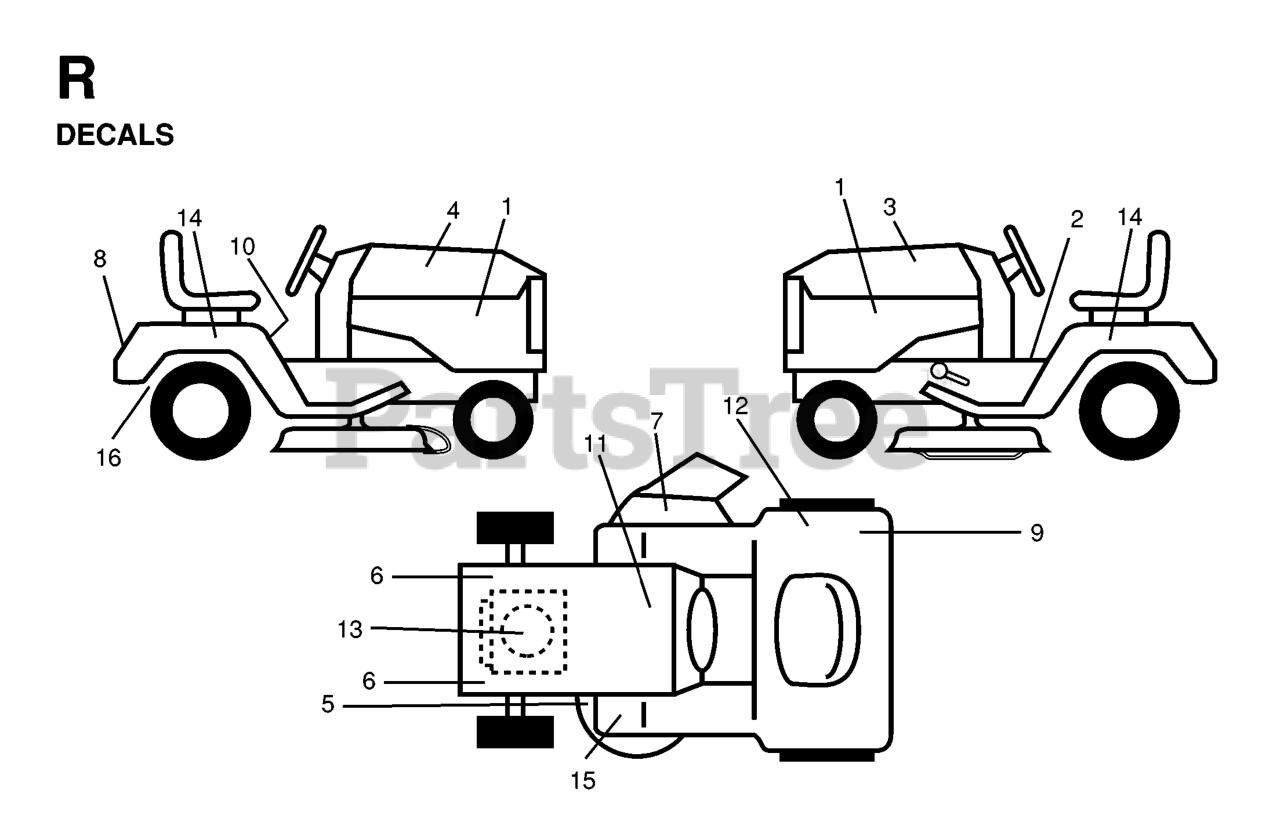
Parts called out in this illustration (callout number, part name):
1	DECAL PNL SIDE
2	DECAL PARK BRAKE
3	HOOD DECAL LH
4	HOOD DECAL RH
5	DECAL V BELT SCHEMATIC
6	DECAL
7	DECAL MOWER CUT/FINGER
8	DECAL FENDER HUSQ
9	DECAL
10	DECAL READ OWNER'S MAN SYMS
11	DECAL BTRY SYMBOLS
12	DECAL EUROPE STANDARD CE
13	DECAL HP ENGINE
14	DECAL
15	DECAL
16	DECAL
